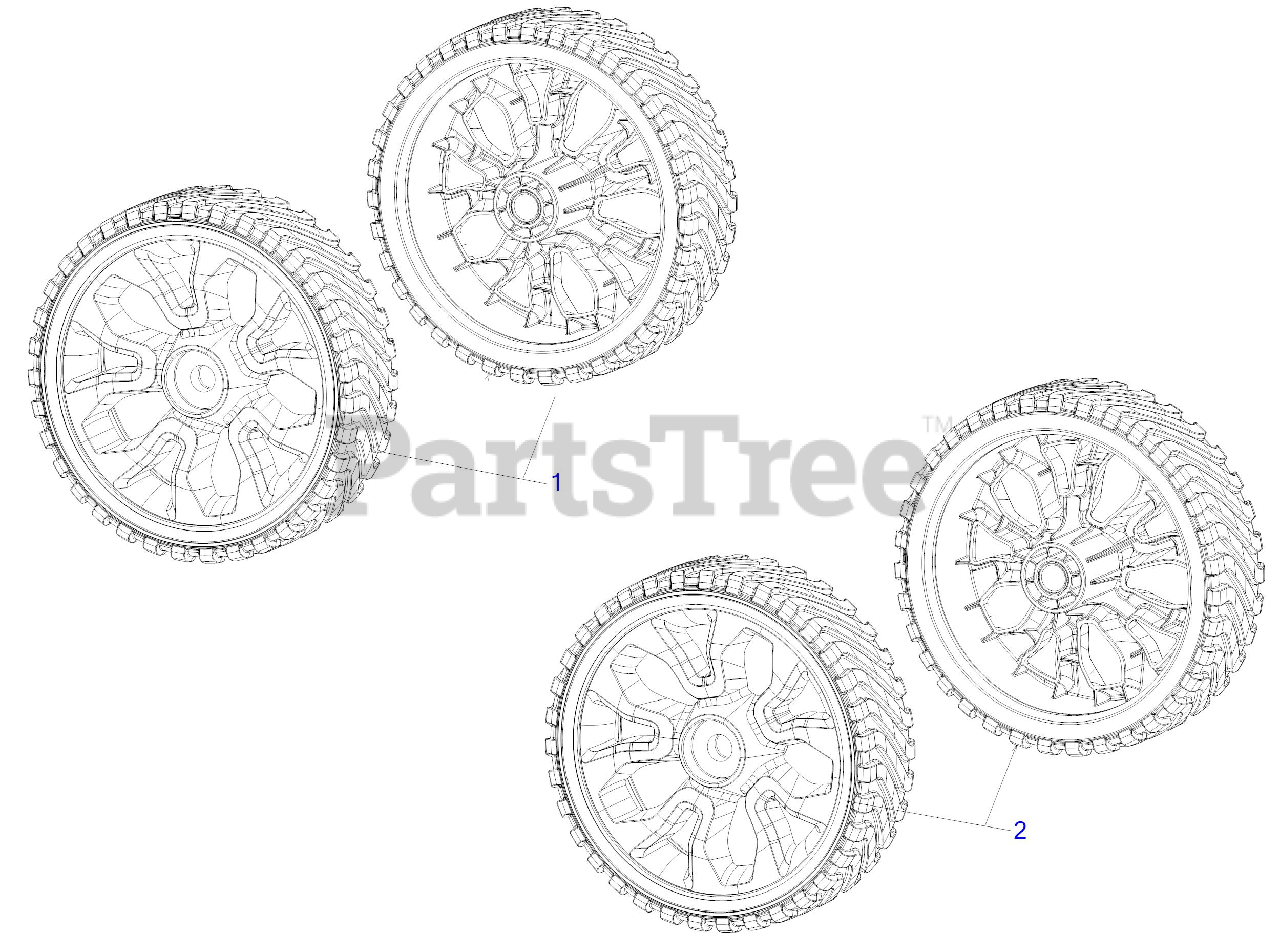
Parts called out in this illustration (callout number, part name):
1	WHEEL ASSEMBLY 8 X 2 GRAY
1	Troy-Bilt IDLE WHEEL ASSEMBLY (8x2x1/2) (GREY)
2	WHEEL ASSEMBLY 7 X 2 GRAY
2	Genuine Factory Parts WHEEL ASSEMBLY (7x2x1/2)(GRAY)
